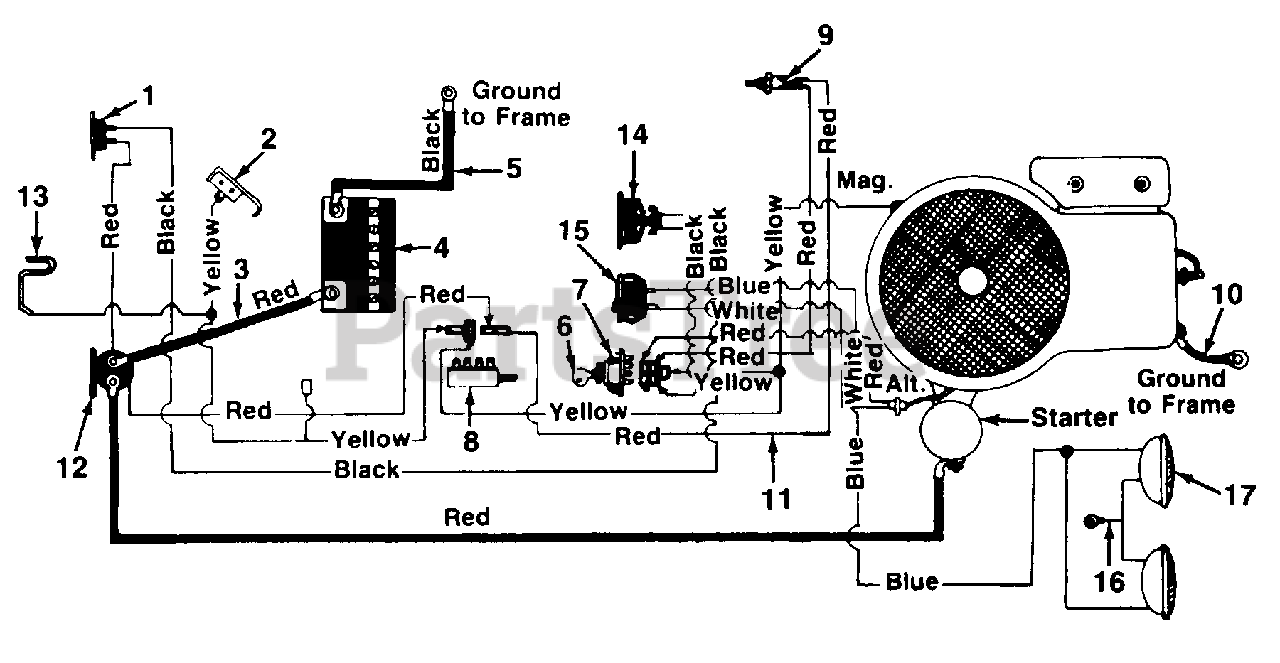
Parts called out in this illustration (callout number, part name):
1	Circuit Breaker
2	Reverse Safety Switch
3	Electric Wire w/Boot
4	12V-Battery
5	Ground Wire 9.0" Lg.
6	Ignition Key
7	Ignition Switch
8	Safety Switch
9	Safety Switch
10	Ground Wire 7.25" Lg.
11	Wire Harness
12	Solenoid
13	Spring Switch
14	Ammeter
15	Light Switch
16	Ground Wire
17	Headlight
